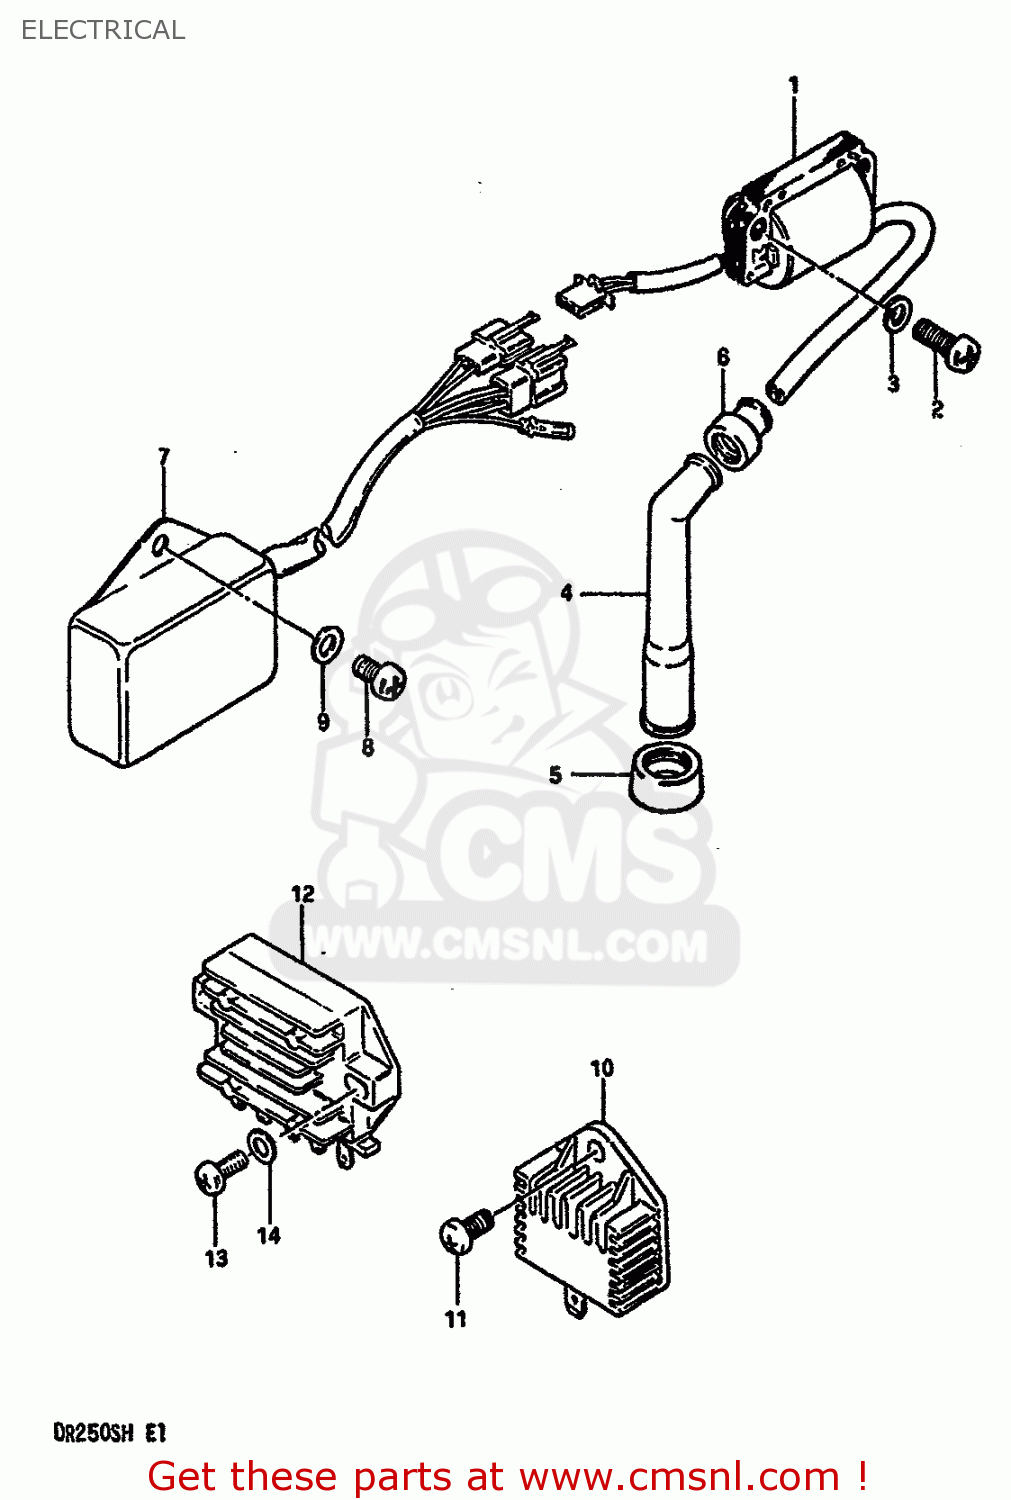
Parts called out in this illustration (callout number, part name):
1	COIL ASSY,IGNITION
2	SCREW
3	WASHER,LOCK
4	CAP ASSY,SPARK PLUG
5	SEAL,SPARK PLUG CAP
6	SEAL,SPARK PLU
7	IGNITER UNIT
8	SCREW
9	WASHER
10	RECTIFIER ASSY,REGULATOR
11	SCREW 6X12
12	RECTIFIER ASSEMBLY
13	SCREW
14	WASHER
